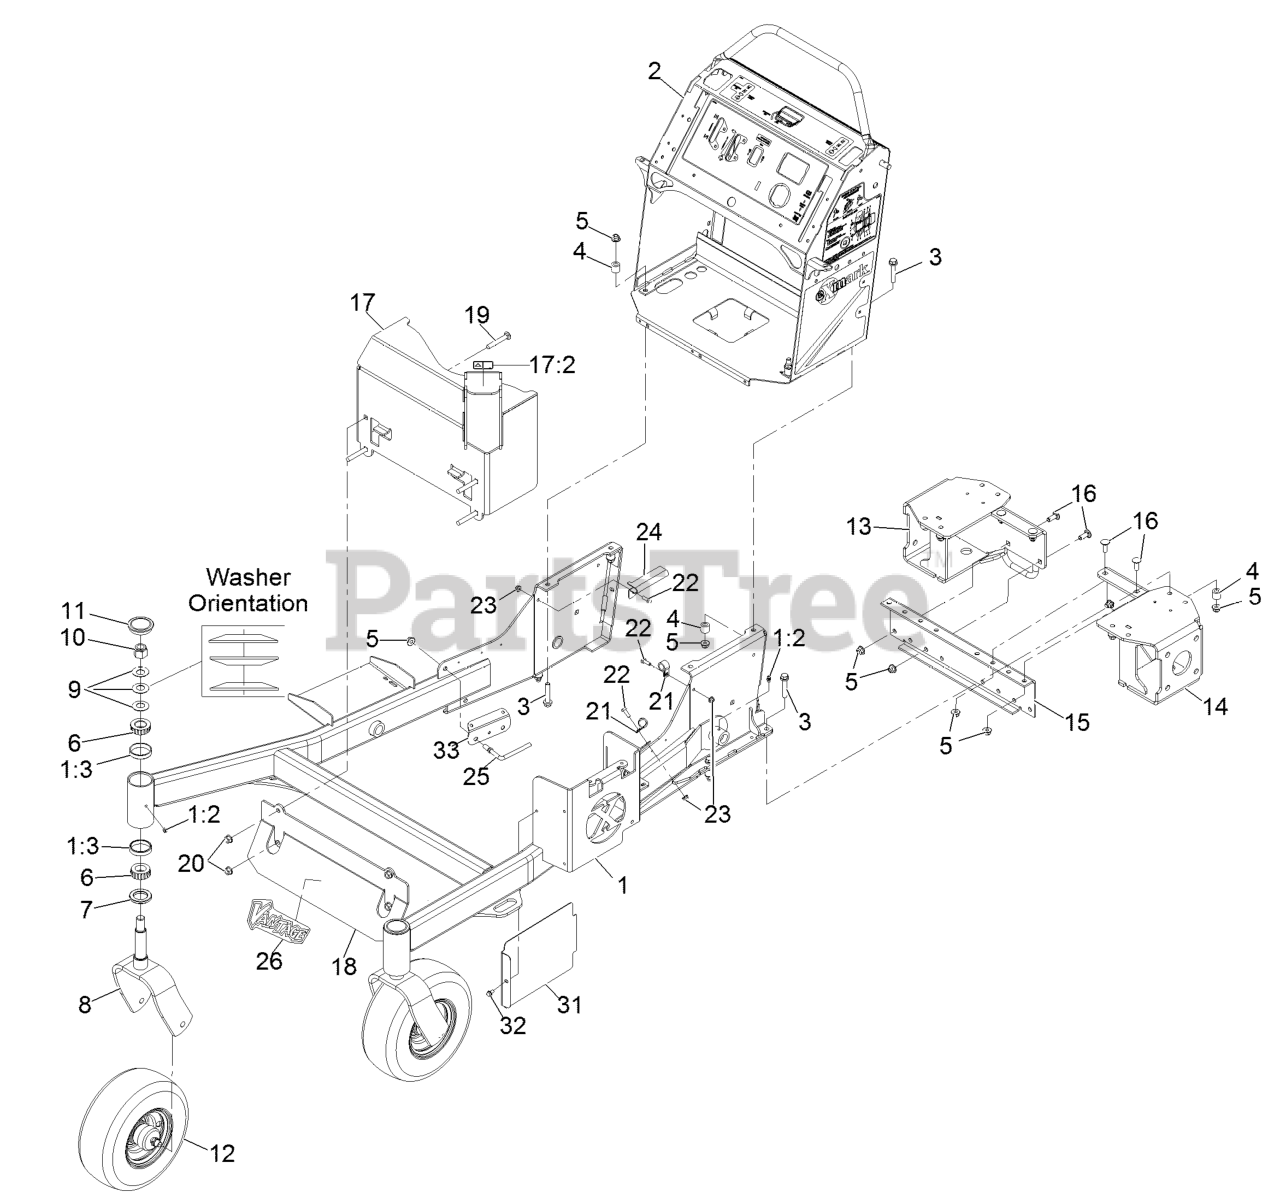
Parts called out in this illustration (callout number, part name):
1	FRONT FRAME ASM
1:2	FITTING-GREASE
2	CONTROL TOWER ASM-EFI
3	SCREW-HHF
5	NUT-HF, NI
6	Cone-Bearing Tapered Roller
7	SEAL-GREASE
8	FORK-CASTER
9	WASHER-BELLVILLE
10	NUT-LOCK, NI
11	CAP-GREASE
12	WHEEL/TIRE AND BEARING AS
13	RH MOTOR MOUNT ASM
14	LH MOTOR MOUNT ASM
15	MOUNT-MOTOR, CENTER
16	SCREW-CARR
17	MUFFLER GUARD ASM
17:2	DECAL-WARNING
18	PANEL-GUARD
19	SCREW-CARR
21	CLAMP-CABLE
22	SCREW-HH
24	BRACKET-HOSE, FUEL
25	GUIDE-HOSE, SUPPORT
26	DECAL-VANTAGE LOGO
31	SHIELD-HEAT, TALL
32	SCREW-HWH
33	GUARD-HOSE
